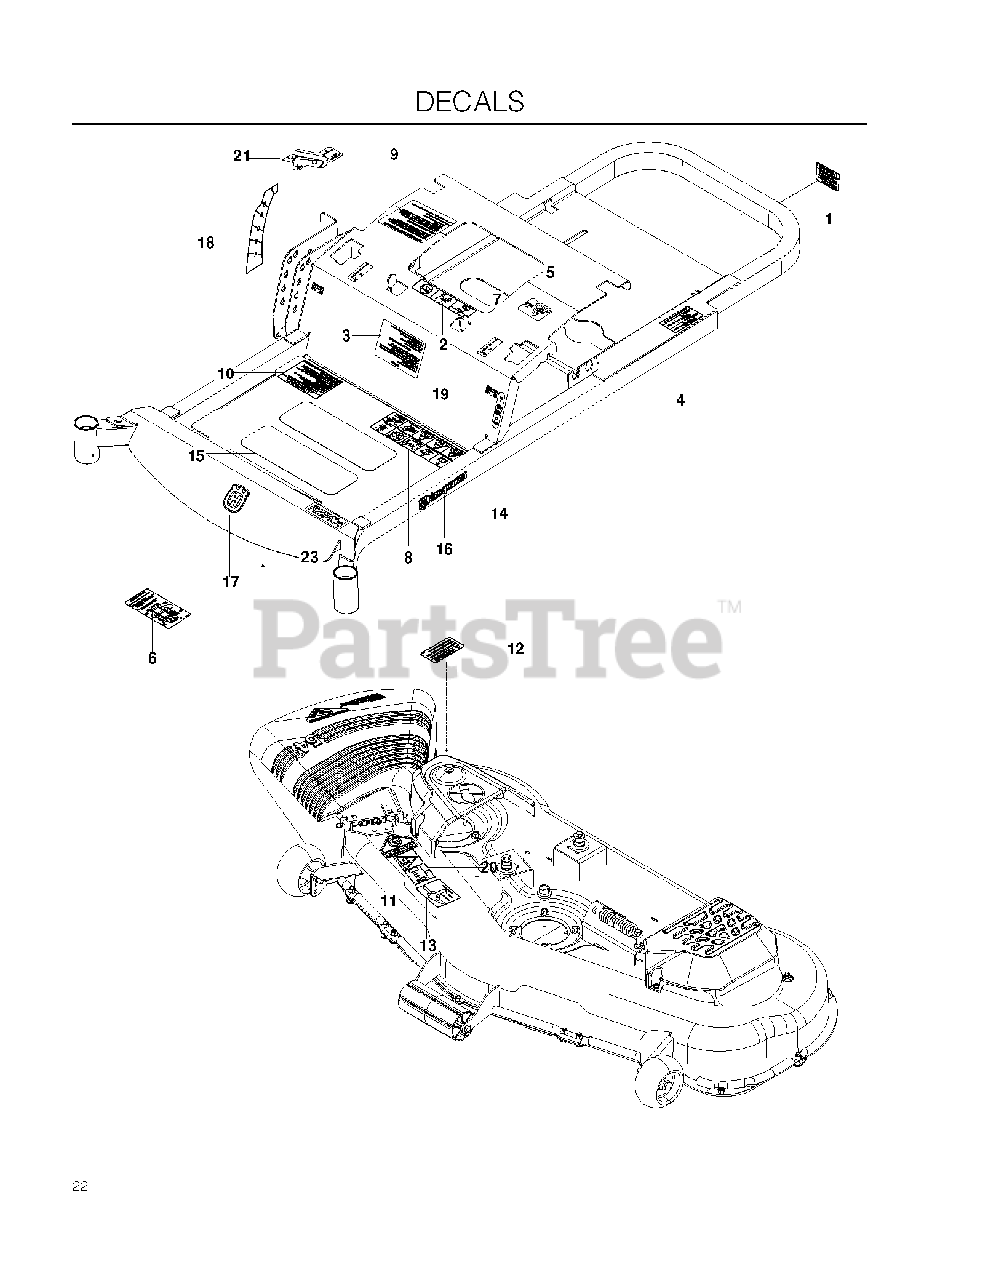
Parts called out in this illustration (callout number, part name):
1	DECAL, PROP. 65
2	EURO DECAL-BATTERY WARNIN6
3	DECAL, START
4	DECAL, DO NOT TOW
5	DECAL, EXITING MOWER
6	DECAL, SERVICE
7	DECAL, MOTION CONTROL
8	DECAL, SAFETY WARNING
9	DECAL, CUSTOMER RESPNSIBILITY
10	DECAL, WARNING
11	DECAL, CPSC
12	DECAL, CAUTION
13	DECAL, BELT ROUTING
14	DECAL, PARK BRAKE
15	ANTI-SKID PAD
16	RP.DECAL.BADGE.170MM.TEXTLOGO
17	DECAL.AUGER.HUSQ.CROWN.SNOW
18	DECAL, DECK HEIGHT, HUSQ
19	DECAL, F.S.T.
20	DECAL, EURO SEVERING
21	DECAL, CTRL PANEL, HUSQ
22	DECAL, RZ5424
